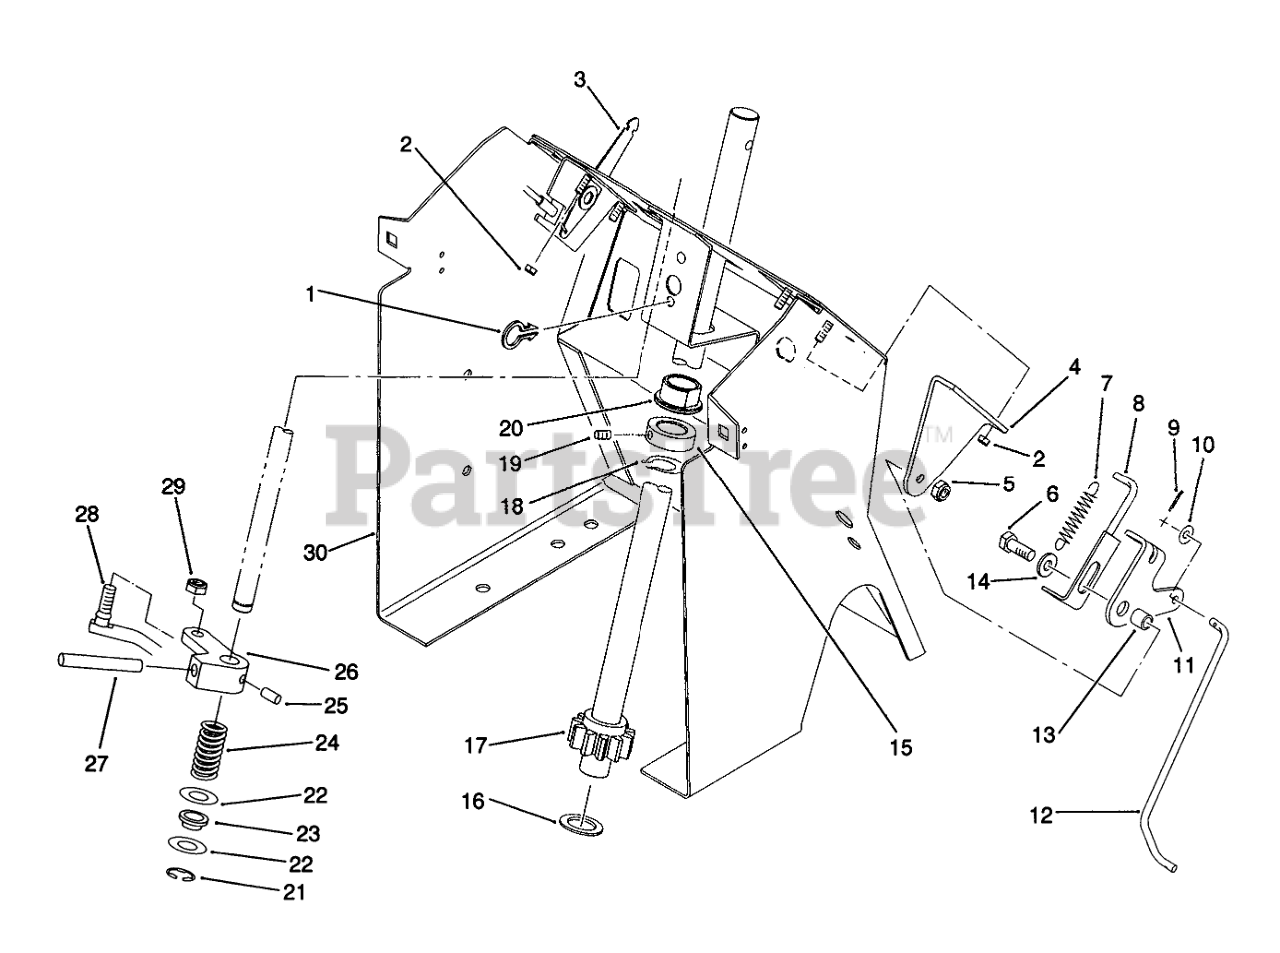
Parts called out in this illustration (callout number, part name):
1	CLIP-SNAP IN
2	Nut
3	Control-Throttle
4	SUPPORT-INDICATOR B
5	Nut
6	Screw-Cap Hex Hd
7	SPRING-EXTENSION
8	WLDMT-INDICATOR R
9	Pin-Cotter
10	Washer
11	RETAINER-INDICATO B
12	ROD-INDICATOR
13	SPACER
14	Washer
15	BEARING-FLANGED
16	WASHER
17	WLDMT-STRG SHAFT
18	RING-RETAINING
19	SCREW-SET
20	COLLAR
21	Snap Ring
22	SHIM-WASHER
23	BUSHING-NYLINER
24	SPRING-COMPRESSION
25	Pin-Roll
26	ARM-SPEED CONTROL
27	PIN-SPIROL 5/16X2.25
28	ROD-SHIFT R
29	Nut
30	Hood Stand
